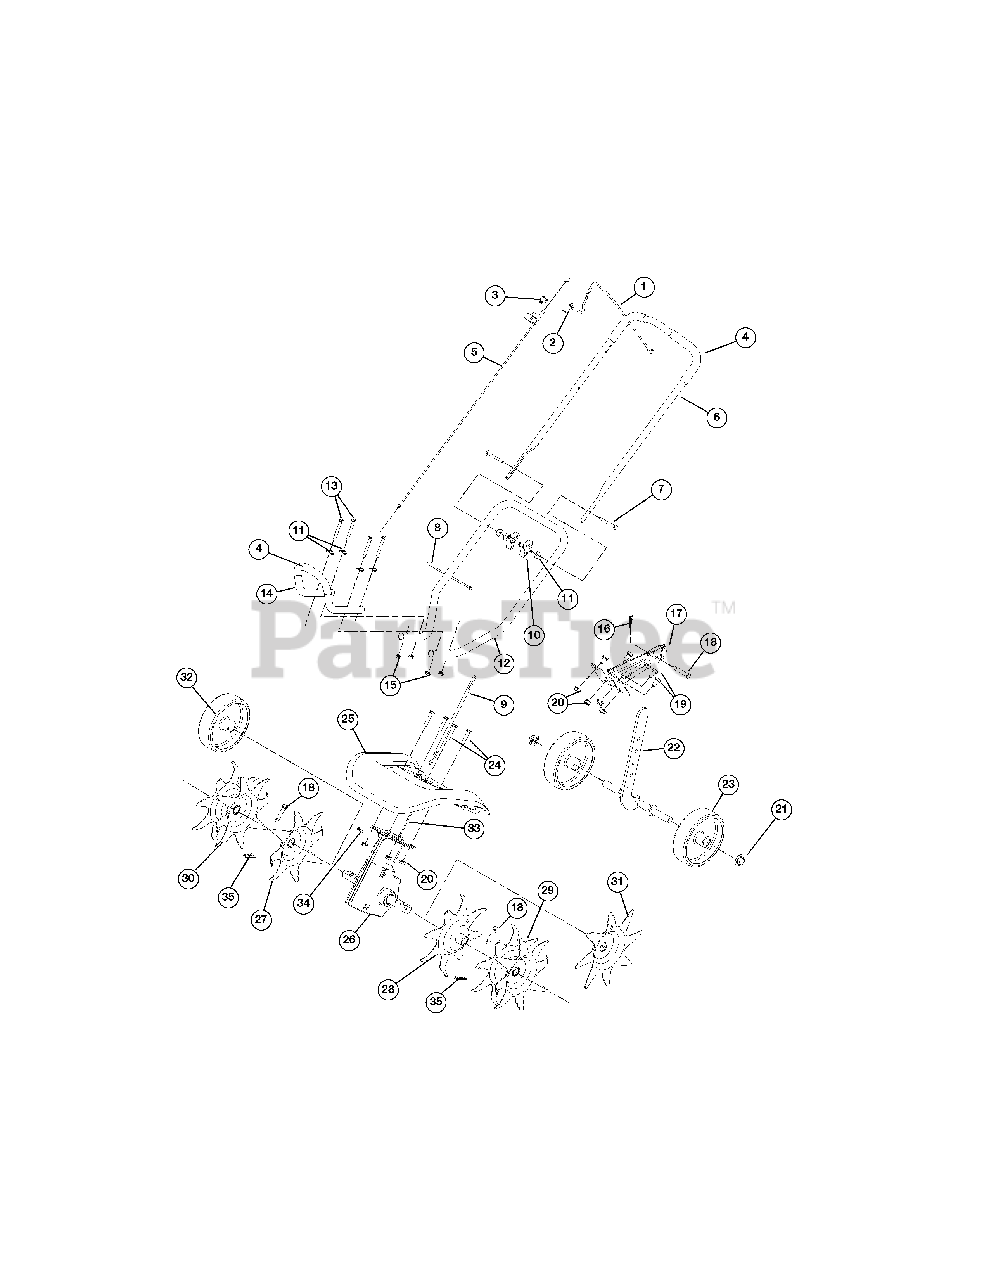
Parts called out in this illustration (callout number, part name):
1	Throttle Control
2	Torsion Spring
3	On/Off Switch
4	Foam Grip
5	Throttle Cable
6	Upper Handle
8	Cable Tie
9	Flex Shaft
11	Washer
13	Screw
14	Front Handle
16	Cotter Pin
17	Tailpiece Bracket Assembly
18	Clevis Pin
19	Cap Screw
22	Wheel Support Bracket Assembly
23	Wheel
25	Tine Shield
26	Gear Box Assembly
27	Tine (Right Outer)
28	Tine (Left Inner)
29	Tine (Left Outer)
30	Tine (Right Outer)
31	Edger Tine
32	Edger Wheel
33	Drive Shaft Housing
34	Sleeve Retaining Bolt
